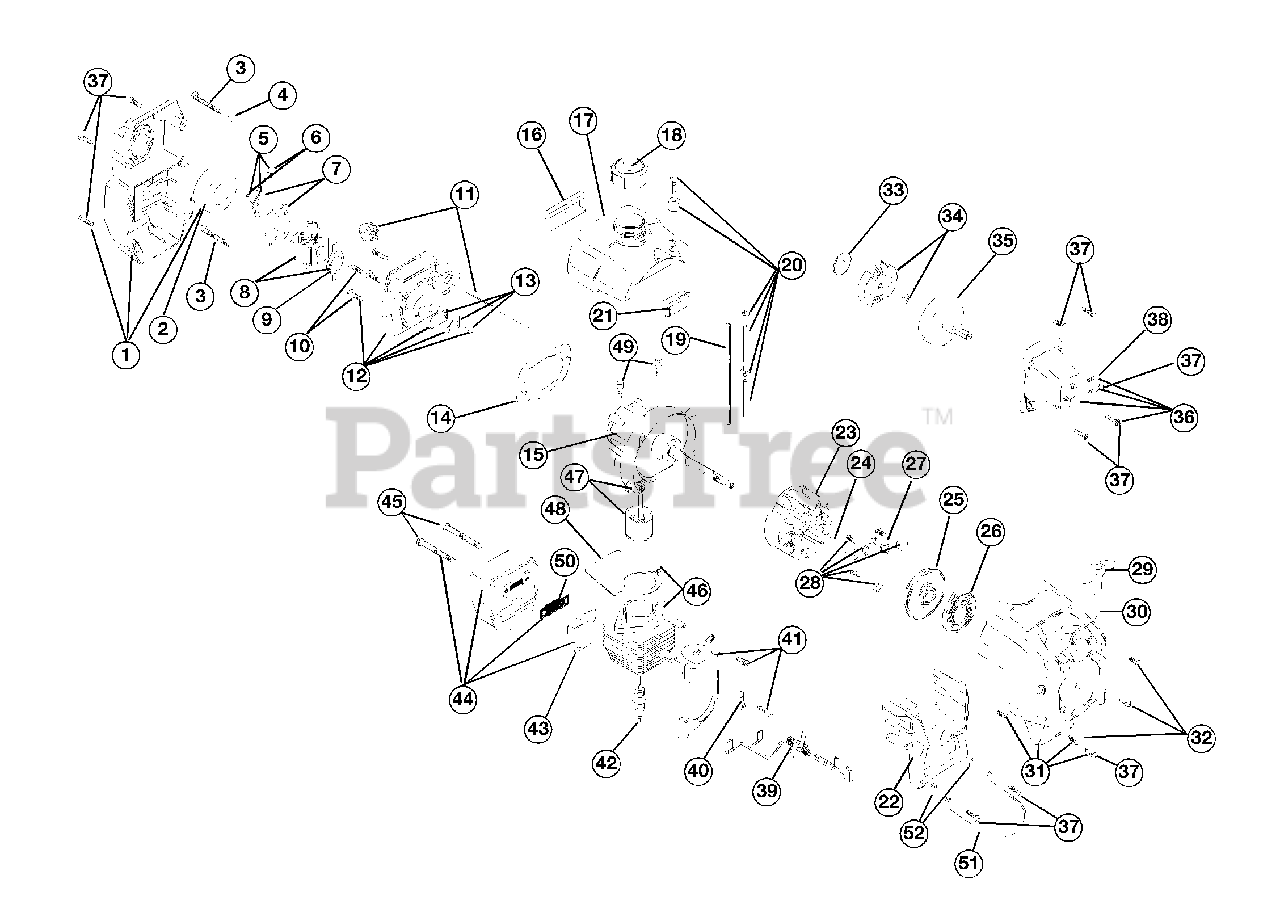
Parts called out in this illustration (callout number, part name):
1	Air Cleaner/Muffler Cover Assembly
2	Air Cleaner Filter
3	Carburetor Mounting Screws
4	Wavey Washer
5	Choke Lever Assembly
6	Choke Knob and Screw
7	Choke Lever and Plate
8	Carburetor Assembly
9	Carburetor Gasket
10	Carb Mount Screw
11	Primer and Hose Assembly
12	Carb Mount Assembly
13	Reed Assembly
14	Carburetor Mount Gasket
15	Crank Case Service Assembly
16	Rear Mounting Pad
17	Petrol Tank Assembly
18	Petrol Cap Assembly
19	Petrol Return Line
20	Petrol Line Assembly
21	Front Mounting Pad
22	Shroud Extension and Stand
23	Flywheel Assembly
25	Recoil Pulley Assembly
26	Recoil Spring
27	Rope Guide
28	Pulley Retainer Assembly
29	Pull Handle
31	Starter Housing Assembly
32	Housing Screw
33	Clutch Washer
34	Clutch Rotor Assembly
35	Clutch Drum Assembly
36	Clutch Cover Assembly
37	Cover Screw
38	Anti-Rotation Screw
39	Wire Leads
40	Ground Tab
41	Module Assembly
42	Spark Plug
43	Exhaust Gasket
44	Muffler Assembly
45	Muffler Mounting Bolt Assembly
46	Cylinder Assembly
47	Piston and Rod Assembly
48	Cylinder Gasket
49	Cylinder Bolt
50	Spark Arrestor Screen
51	Foot Stand
